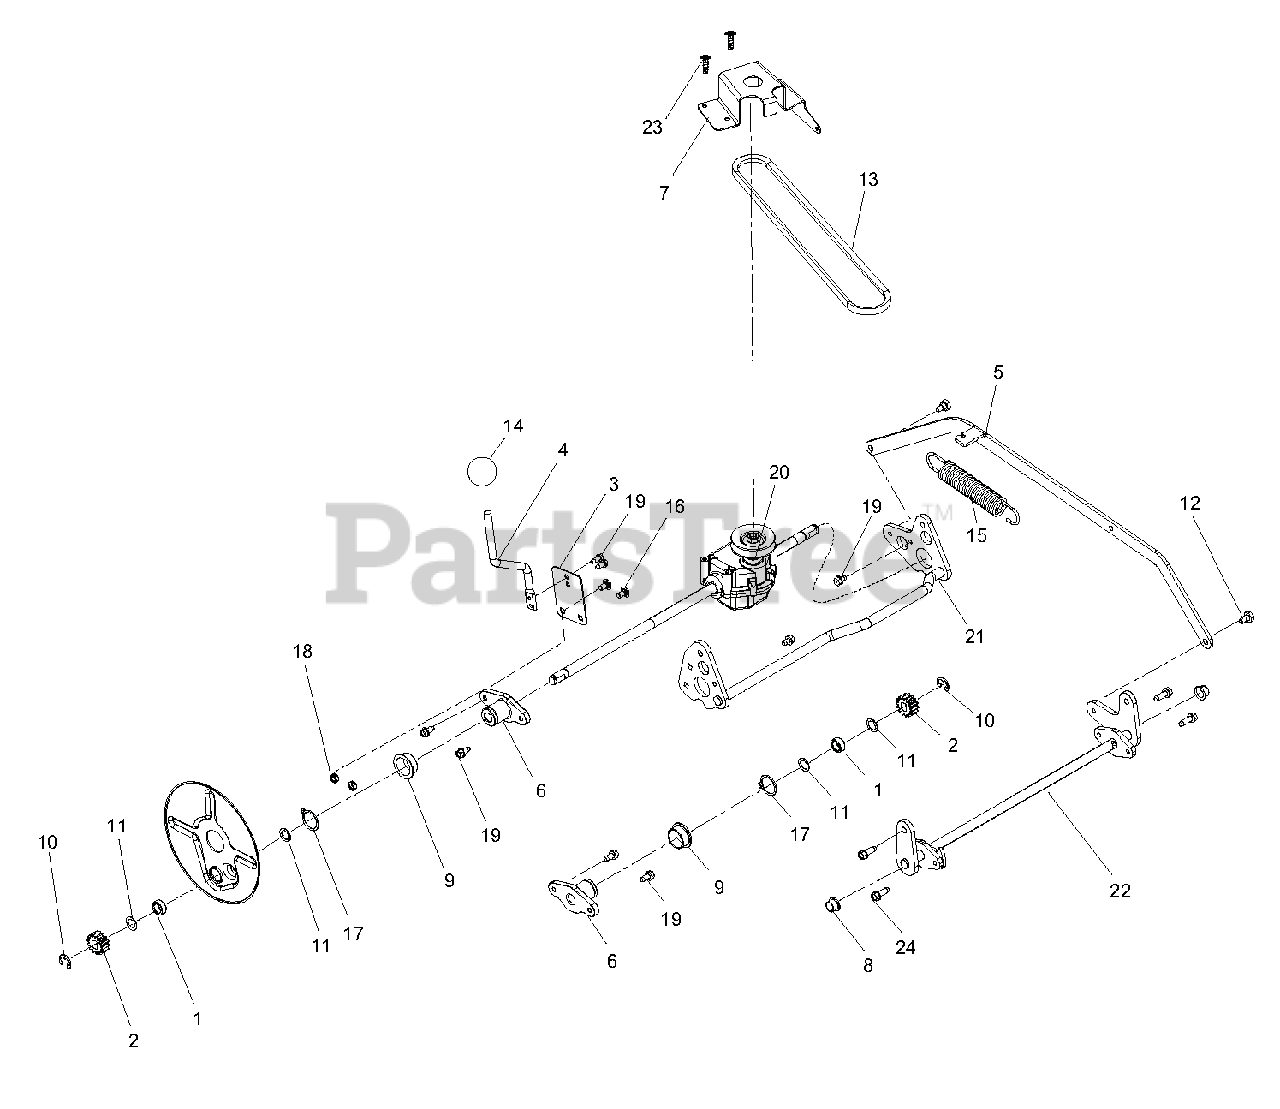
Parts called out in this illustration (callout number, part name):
1	BSHG, SPCR.500X.750X.321 PM
2	GEAR, PINION, LM WHEEL DRIVE
3	PLATE, HOC SPRING
4	LEVER, HOC ADJUSTMENT
5	LINK, HOC CONNECT
6	HUB, LM REAR AXLE
7	BRKT, BELT GUIDE
8	BUSHING, POLYLINER-.50 SPLIT
9	BSHG-FLG 1.0X1.125X.50X1.375 R
10	RG-RTNG-EXT .500X.042 (E)
11	WASHER, .500X.750X.020 THRUST
12	BOLT, SHLDR .320X.210X.25-20
13	V-BELT, 3L-WRAPPED
14	KNOB,BALL -BLACK 1.47" .375-16
15	SG-TENS .121X1.00X6.5 WLD 12
16	@BLT-RDHDSQNK .25-20X.50 G5YZ
17	RG-RTNG-EXT 1.00X.042
18	NUT-LK-CTR JAM .25-20 YWZC
19	SCR-TAP .25-20X.50 HWH TR YWZ
20	TRANSAXLE, AUTOMATIC, LM, 9:1
21	WMT,RR AXL(SEE BULLETIN B2119)
22	WMT, LM FRONT AXLE
23	SCR-TAP 10-14X.75PLSTITE BLKOX
24	SCR-TAP-PM .25-20X.75 TR YWZ
